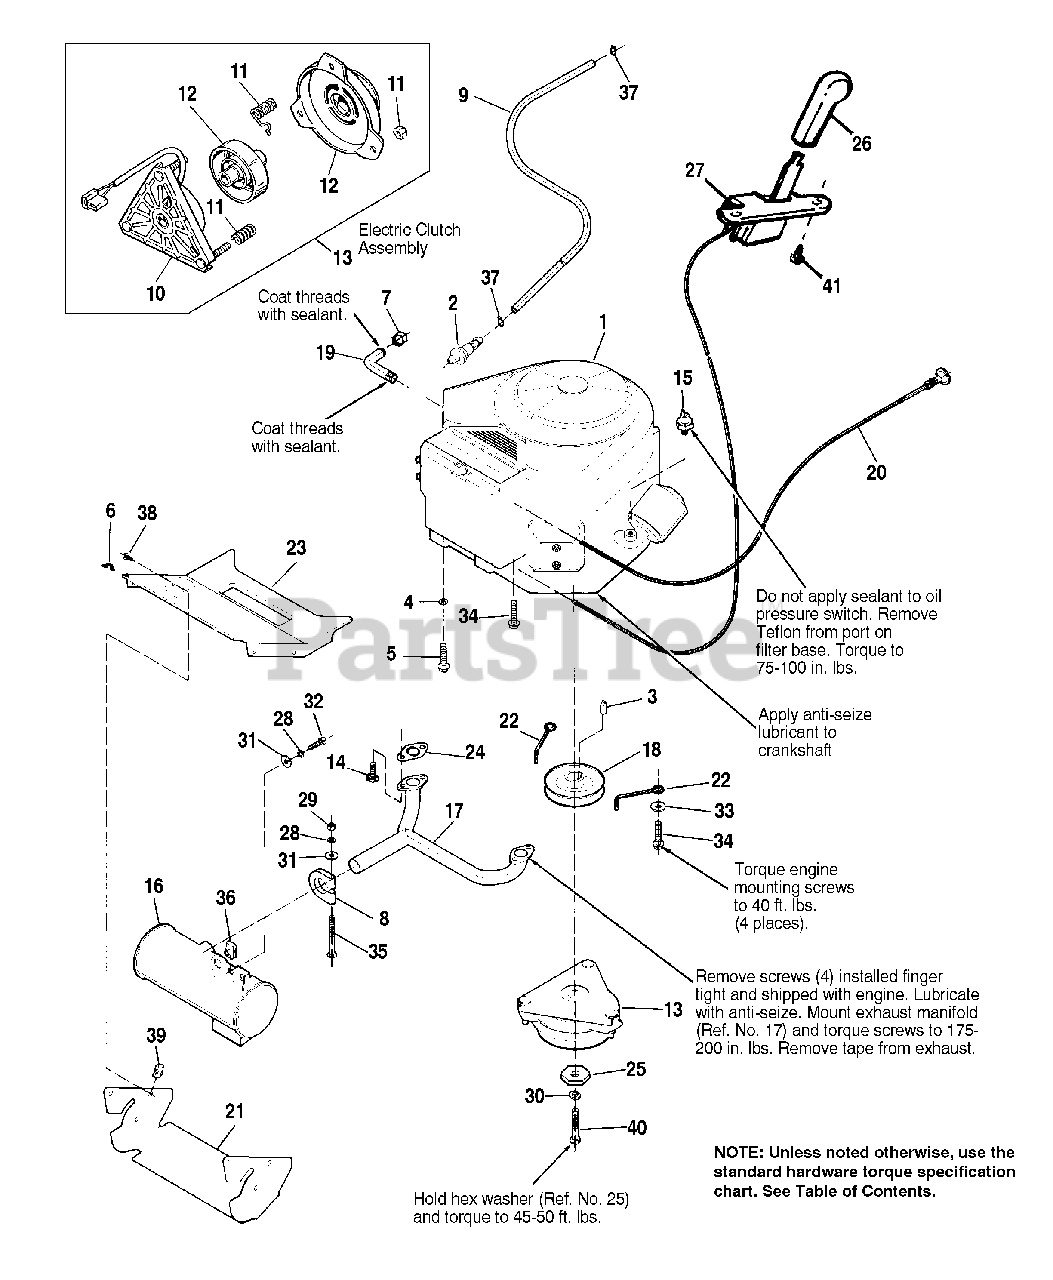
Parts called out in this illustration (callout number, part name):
1	ENGINE, Twin Cylinder
2	FUEL FILTER
3	KEY, Hi-Pro
4	LOCKWASHER, External Tooth
5	SCREW, Taptite, 3/8-16 x 1-1/2
6	CLIP
8	CLAMP, Muffler
9	HOSE, Fuel, 45-1/2" Long
10	FIELD ASSY., Clutch
11	SPRING & NUT KIT
12	ROTOR & ARMATURE ASSY.
13	ELECTRIC CLUTCH
14	SCREW, Metric
15	SWITCH, Oil Pressure
16	MUFFLER ASSY.
17	MANIFOLD, Exhaust
18	PULLEY ASSY.
20	CABLE, Choke Control
21	DUCT, Lower Muffler
23	DUCT, Upper Muffler
24	GASKET, Exhaust Manifold
25	WASHER, Hex
26	KNOB, Throttle
27	THROTTLE CONTROL ASSY.
28	LOCKWASHER, 5/16
29	NUT, Hex, Full, 5/16-18
30	LOCKWASHER, 7/16
31	WASHER, Plain, 11/32
32	CAPSCREW, Hex, 5/16-18 x 1
33	WASHER, Plain, 13/32
34	SCREW, Taptite, 3/8-16 x 1-1/2
35	CARRIAGE BOLT, 5/16-18 x 2-3/4
36	PAL NUT, 5/16-18
37	CLAMP, Hose
38	SCREW, Flange, Whizlock, 1/4-20 x 5/8
39	PAL NUT, 1/4-20
40	CAPSCREW, 7/16-20 x 2-1/2
41	SCREW, Hex, Washer Hd., Plastite, 1/4-20 x 1/2
